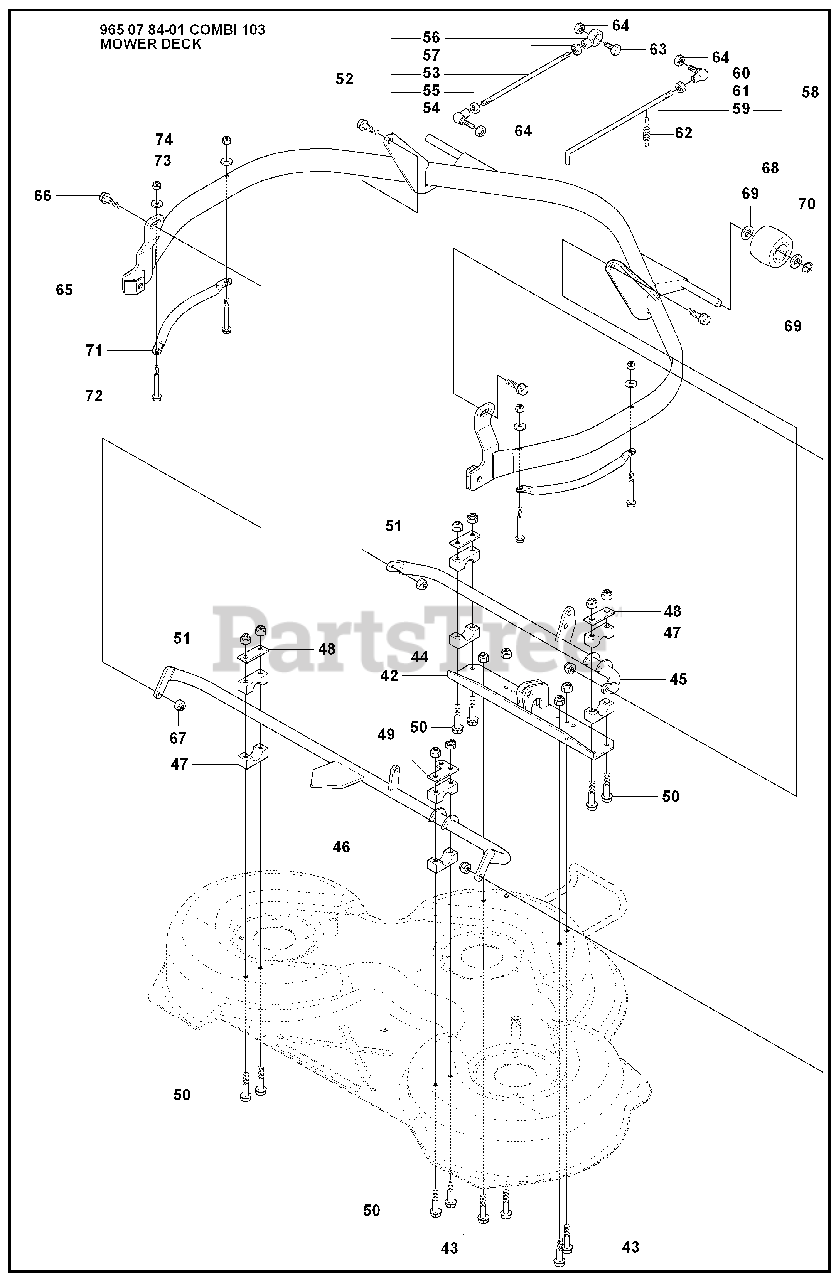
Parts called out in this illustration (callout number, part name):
44	LOCKNUT M8
51	LOCKNUT M8
52	PARALLEL RODY ASSY
57	NUT
58	CLUTCH ROD ASSY
64	NUT
65	PROTECTIVE TUBING
67	LOCKNUT M8
68	DECK ROLLER, FRONT
70	RETAINING RING SGA 15
73	WASHER
74	LOCKNUT M6
